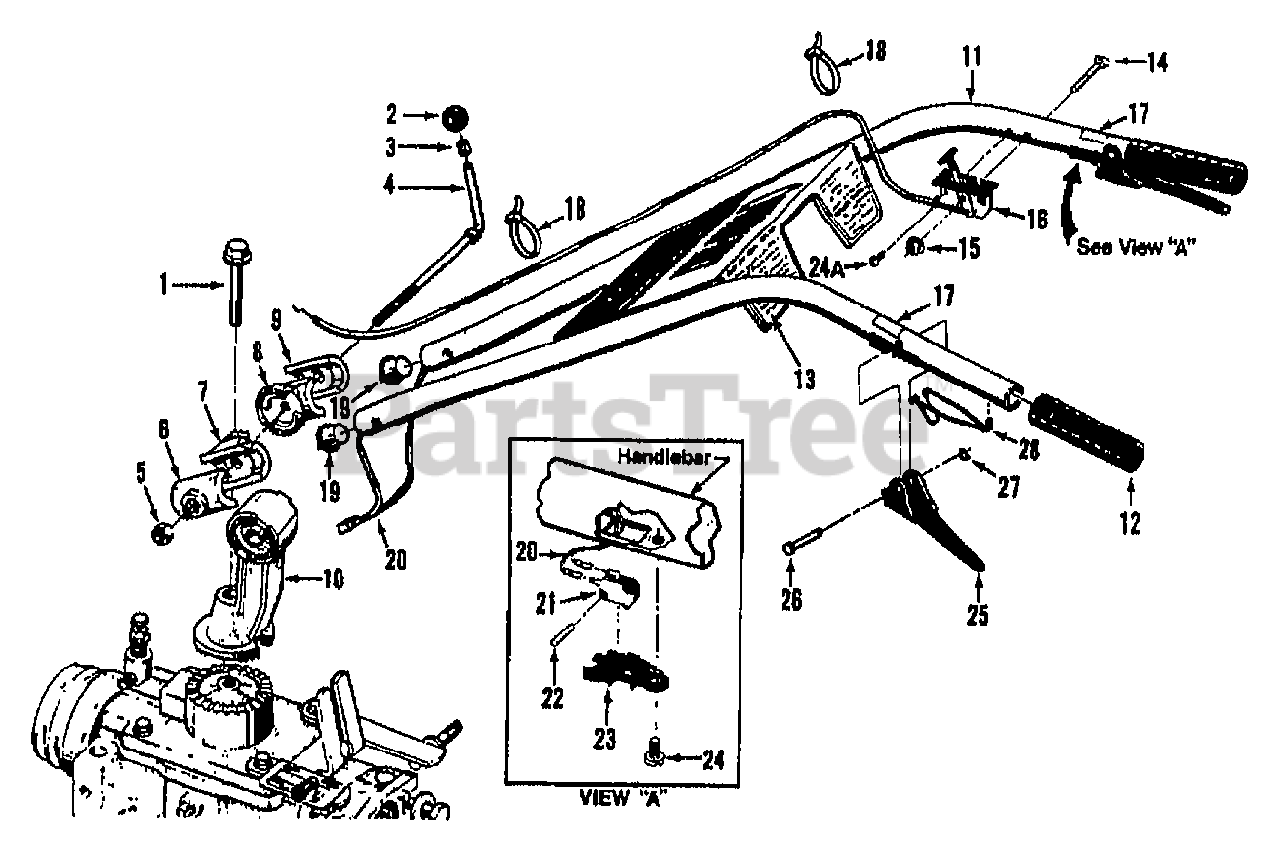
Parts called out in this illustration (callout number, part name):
1	BOLT 1/2-13X3.5 FH GR5
2	KNOB-CONTROL (INCL. 3)
3	RING-TOLERANCE .5325 ID
4	STUD-H/BAR BLACK (INCL. # 2,3, & 5)
5	NUT-HEX JAM 1/2-13
6	CLAMP-H/BAR LH BLACK
7	RATCHET-H/BAR LH BLK
8	RATCHET-H/BAR RH BLK
9	CLAMP-H/BAR RH BLACK
10	BASE-H/BAR BLACK
11	ASSM-H/BAR BLACK (INCL. 2 EA. #12,17, & 28 & 1 #13)
12	GRIP-H/BAR SMOOTH
13	DECAL-CONTROL PANEL
14	BOLT-CH 1/4-20X2.00 ZP
15	NUT-HF/LK 1/4-20 ZP
16	CABLE-THROTTLE 8HP OPC
17	DECAL-FWD INTERLOCK
18	TIE-RED
19	RETAINER-HARNESS H/B OPC
20	HARNESS-WIRE OPC HORSE
21	SWITCH-H/B OPC
22	PIN-LK .11X.58 HORSE OPC
23	HOUSING-SWITCH OPC
24	SCR-HW M10-24X.5 STH ZP
24A	THIS REF NO. NOT USED WITH KOHLER ENGINE
25	LEVER-HORSE OPC
26	PIN-PIVOT OPC LEVER
27	RING-KLIP 5304-25
28	SPRING-H/B LEVER
